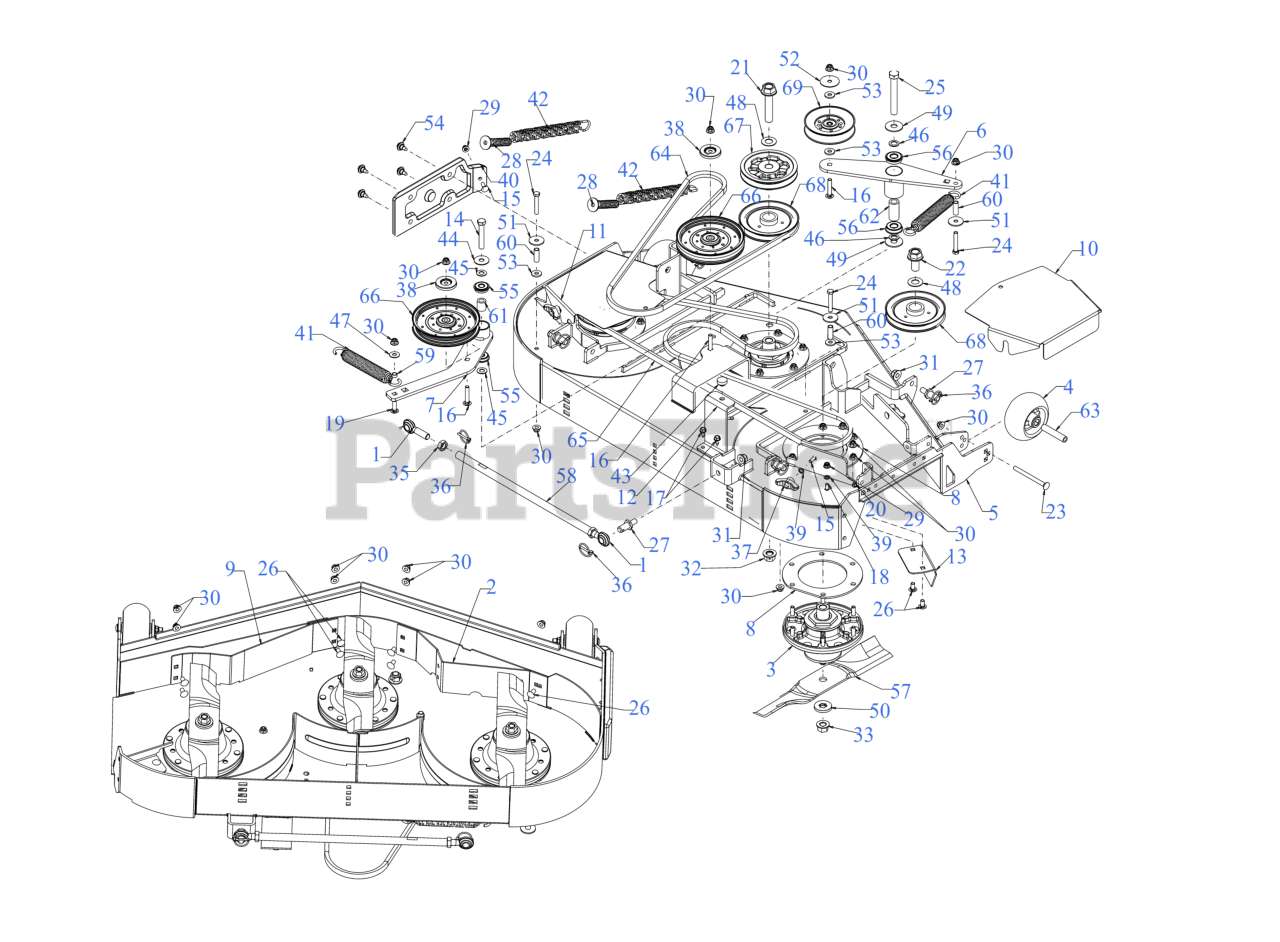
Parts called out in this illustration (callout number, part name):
1	MALE ROD END
2	48" ADJUSTMENT BAFFLE
3	SPINDLE ASSEMBLY
4	5" DIA DECK WHEEL COMPLETE
4	WHEEL BUSHING
5	48" FAB DECK
6	IDLER BRACKET
7	48" DECK IDLER BRACKET
8	SPINDLE SUPPORT BRACKET TOP/BTM
10	BELT COVER (RH)
11	BELT COVER (LH)
12	DECK STOP BRACKET
13	DECK CHUTE BAFFLE
14	SCREW-HEX 1/2-13 x 3.00
15	CARRIAGE BOLT 5/16-18 x 1.00
16	CARRIAGE BOLT 3/8-16 x 2
17	SCREW 5/16-18 x .750
18	CARRIAGE BOLT 5/16-18 x .75
19	CARRIAGE BOLT 3/8-16 X1.25 GR5
20	SCREW 1/4-20 X.500
21	CAP SCREW-HHFLG 3/4-10 X 3.50 GR8
22	CAP SCREW-HHFLG 3/4-10 X 1.50 GR8
23	CARRIAGE BOLT 3/8-16 x 4.25 GR5
24	SCREW 3/8-16 x 2.25 GR5
25	SCREW 5/8-18X4.5 GR5
26	CARRIAGE BOLT 3/8-16 x .75
28	SPRING INSERT SCREW
29	FLANGE LOCK NUT 5/16-18
33	FLANGE NUT - 5/8-18 GDE 8
34	HEX NUT CTR LK 1/2-13
35	HEX JAM NUT 5/8-18
36	LYNCH PIN .1875
37	WING KNOB 5/16-18
38	PULLEY CAP
40	DECK SKID PLATE (LH)
41	SPRING 1.25" DIA x 8.5" LONG
42	EXTENTION SPRING 1.20 x 11.35
43	RUBBER BUMPER 1.000 x .313
44	FLAT WASHER
45	FLAT WASHER .510X.995
46	FLAT WASHER
47	WASHER-.395 x 1.0 x .62
48	FLAT WASHER
49	FLAT WASHER 0.635xX1.755x0.110
50	FLAT WASHER - SPECIAL
51	FLAT WASHER .406X1.5X11
52	HUB CAP WASHER .406 x 1.92 x .060
53	FLAT WASHER .406ID X1.0 OD
54	SHOULDER SCREW .43X.29X5/16-18 TT
55	ROLLER BEARING .5X1.37X.44
56	BALL BEARING W/RET
57	17" BLADE (HI LIFT)
57	Cub Cadet 48" HI LIFT BLADE SET
57	17" HI-LIFT BLADE 0.756 ID
57	LOW-LIFT 17" BLADE (48"DECK)
57	BLADE-HI LIFT 17.0
57	17" BLADE (MULCH)
58	TUBE .565 X .750 X 18.75"LG
61	SPACER 0.51 x 0.88 x 1.00
62	SPACER 0.63 x 1.00 x 2.01
63	WHEEL SPACER .38ID x 3.04LG
64	BELT B SEC x 87.30
65	BELT B SEC X 109.9
66	IDLER PULLEY
67	DRIVE PULLEY
68	SPINDLE PULLEY 6"
69	IDLER PULLEY 5.06 OD
